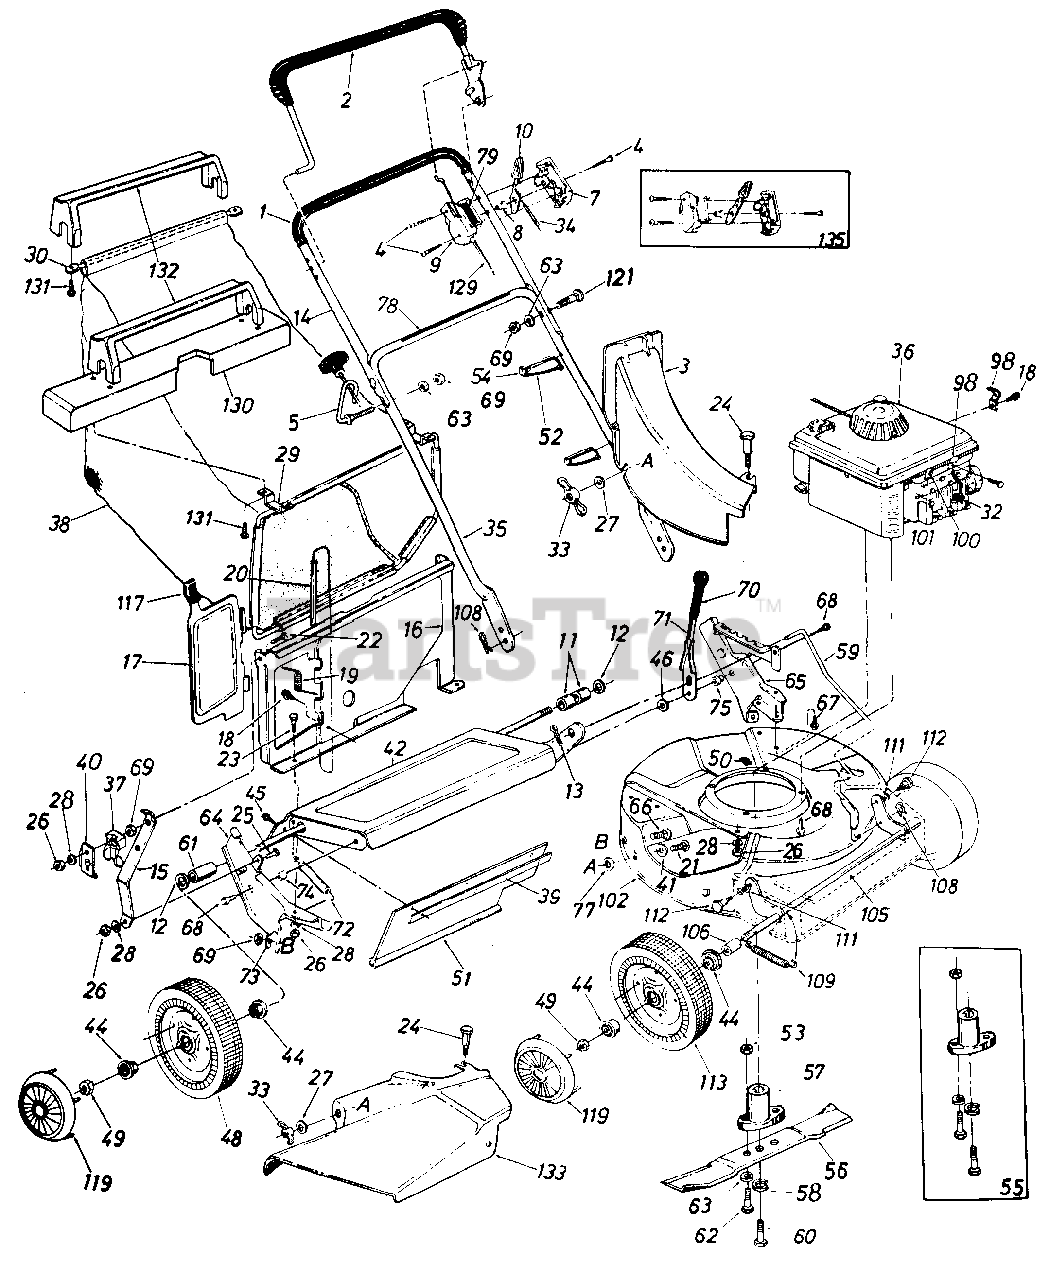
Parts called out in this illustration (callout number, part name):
2	Control Handle Ass'y. L.H.
3	Top Discharge Chute Ass'y.
4	Truss Mach. Scr. #12 x 1.50" Lg.
5	Rope Guide Bolt
7	Control Panel Half
8	Control Disc Pin
9	Clutch Panel Half
10	Throttle Control Lever
11	Spacer .526" I.D. x .690" O.D. x .640" Lg.
12	Fl-Wash. .510" I.D. x .75"
13	Cotter Pin 3/32" Dia. x .75"
14	Upper Handle Chrome
15	Panel Support Brkt.
16	Top Catcher Panel
17	Top Door
18	Hex B-Tap Scr. #10 x .38"
19	Torsion Spring
20	Pivot Pin
21	Carriage Bolt 1/4-20 x .62"
22	Truss Mach. Scr. 1/4-20 x 1.0" Lg.
23	Hex Bolt 1/4-20 x .50" Lg.
24	Shoulder Bolt .312 Dia. x .18 Lg. Special
25	Hex Bolt 1/4-20 x .62" Lg.
26	Hex Nut 1/4-20 Thd.
27	Fl-Wash. .280" I.D. x .620"
28	L-Wash. 1/4" I.D.
29	Front Grass Catcher Frame
30	Upper Bag Support
32	Spark Plug Insulator
33	Wing Nut
34	Throttle Control Wire 45"
35	Lower Handle Chrome
36	Engine
37	Rope Guide Half
38	21" Top Discharge Grass Bag
39	Retaining Strip
40	Rope Retainer Spring Clip
41	Fl-Wash. .344" I.D. x .62"
42	Rear Axle Ass'y.
44	Flange Ball Bearing1/2" I.D.
45	Hex AB-Tap Scr. 1/4 x .62"
46	Fl-Wash. .38" I.D. x 1.0"
48	Rear Wheel Ass'y. Comp. 8 x 1 .75
49	Hex L-Nut 1/2-20 Thd.
51	Rear Flap 3.75" x 17.30" Lg.
52	Cable Tie
53	Hex Nut 5/16-24 Thd.
54	Cable Anchor
55	Blade Adapter Kit
56	21" Blade
57	Blade Adapter
58	L-Wash. 3/8" I.D. H.D.
59	Height Adj. Rod. 19.42" Lg.
60	Hex Bolt 3/8-24 X 2.25" Lg. (Grade 5)
61	Spacer .513" I.D. x .703 O.D. x .69" Lg.
62	Hex Bolt 5/16-24 X 1.00" Lg. (Grade 5)
63	L-Wash. 5/16" I.D.
64	R.H. Handle Wheel Brkt. Ass'y.
65	L.H. Handle Wheel Brkt. Ass'y.
66	Carriage Bolt 5/16-18 X .62"
67	Hex Wash. Hd. B-Tap Scr. 5/1 6-1 8
68	Hex Wash. Hd. TT-Tap Scr. 3/8-16
69	Hex Nut 5/16-18 Thd.
71	Height Adj. Lever
72	Extension Spring .50" O.D. X 3.80" Lg.
73	Bell-Wash. .345" I.D. x .88" O.D.
74	Spacer .385" I.D. x .502" O.D. x .270" Lg.
75	Shld. Spacer .500" Dia. x .100
77	Bolt Retainer 1/4 X .50" O.D.
78	Instruction Label
79	Control Label
98	Casing Clamp
100	Hex B-Tap Scr. #10 x .62"
101	Casing Clamp
102	21" Deck Ass'y.
105	Front Axle Ass'y.
106	Sleeve .526" I.D. x .690" O.D. x .880" Lg.
108	Intern. Cotter Pin 5/16" Dia.
109	Extension Spring .50" O.D. X 3.20" Lg.
111	Intern. L-Wash. 3/8 I.D.
112	Shld. Bolt .623" Dia. x .425
113	Front-Wheel Ass'y. Comp. 7 X 1.50
117	Door Grip
119	Hub Cap Plastic Black
121	Curved Carr. Bolt 5/16-18 X 1.38" Lg.
129	Control Cable 55"
130	Catcher Frame Cover
131	Truss Mach. Tap Scr. 1" Lg.
132	Bag Handle
133	Side Chute Deflector Ass'y.
135	Kit Control Housing Comp.
